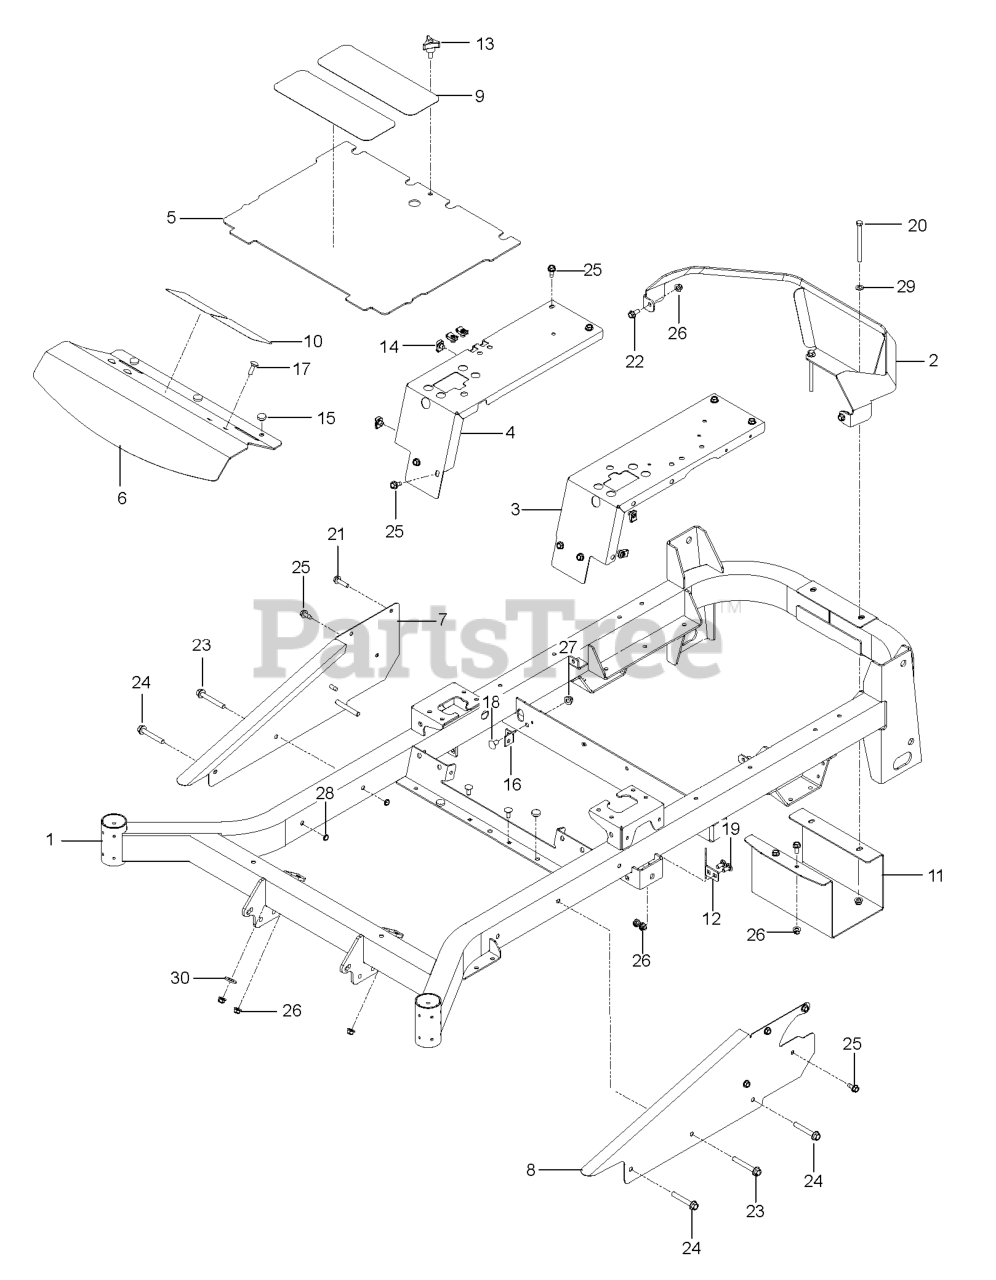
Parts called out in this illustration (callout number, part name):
1	FRAME W/DECALS
2	GUARD, REAR MZ, GRAY
3	PANEL.FILLER.RT.ORNAGE
4	PANEL, FILLER RH ZT, ORG
5	PLATE, FLOOR W/DECALS
6	PLATE, FOOTREST
7	SIDE.RT.ORANGE
8	SIDE.LT.ORANGE
9	ANTI-SKID PAD
11	SHIELD.MUFFLER.BLACK
12	STOP, DECK, EZ+
13	KNOB W/STUD
14	U-CLIP 5/16-18 NUT RETAINER
15	GROMMET, BUMPER
16	BRACKET.DAMPENER.BLACK
18	RHSNB 3/8-16 X 3/4 GR 5 BLK ZN
19	BOLT 5/16C X 3/4" CARRIAGE
20	HCS 5/16C X 4
21	HHFS 5/16-18 X 1.25 TPBLT GD 5
22	HHFS 5/16-18 X 3/4
23	HHFS 3/8-16 X 2 3/4
24	HHFS 3/8-16 X 2.5 GR 5 ZD
25	BOLT 5/16-18 X 3/4
26	5/16-18 NYLOC FLANGE NUT
27	NUT 3/8-16 HEX FLG NYLOC ZD
28	NUT HEX 3/8-16 NYLON, THIN
29	FLAT WASHER 5/16 SAE
30	WASHER 1/2" FLAT
